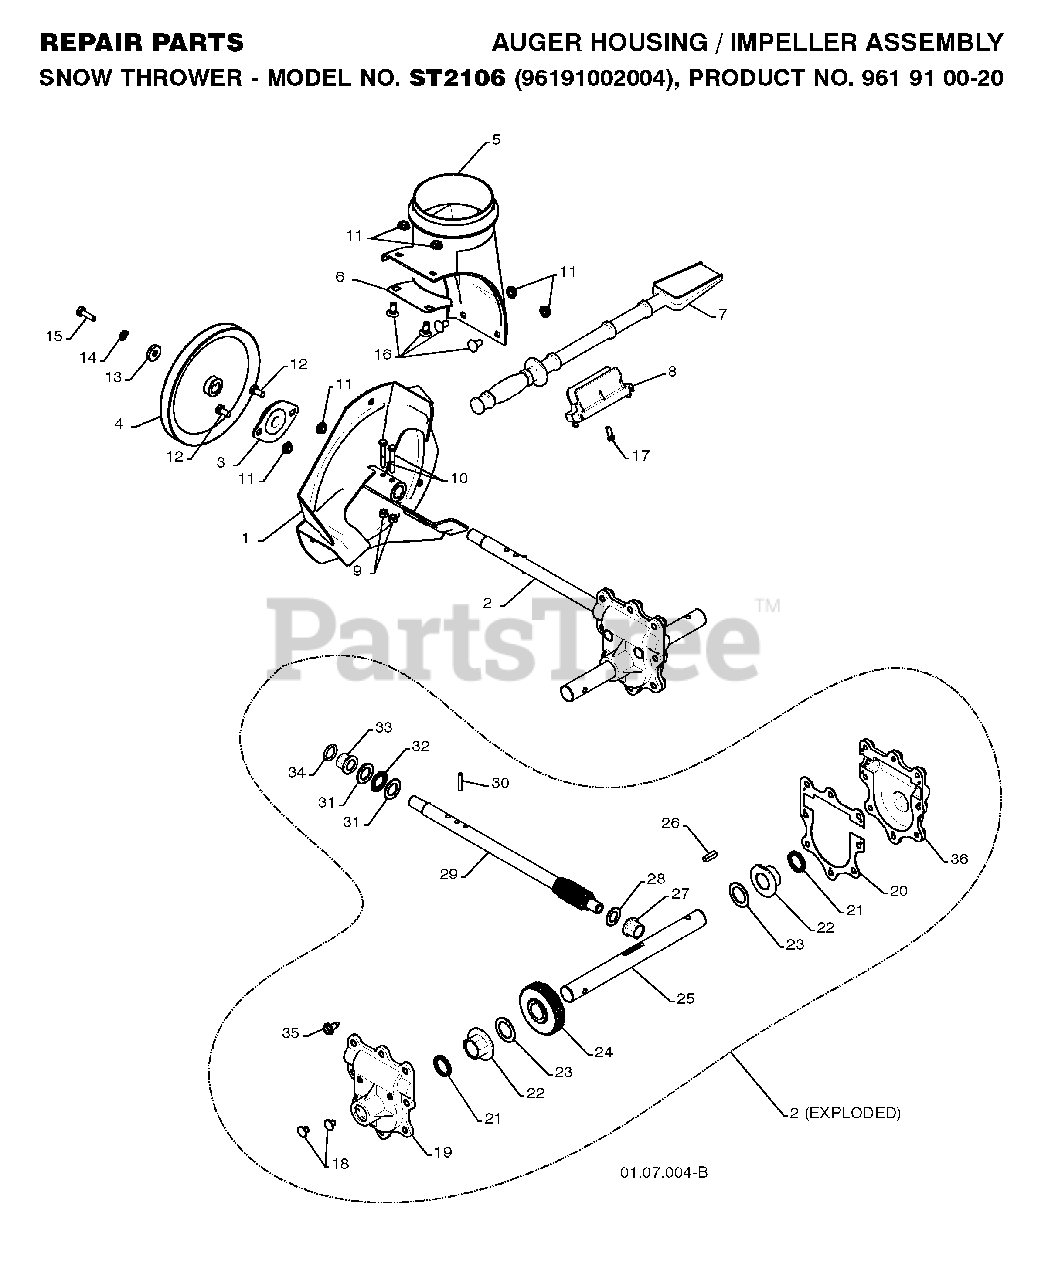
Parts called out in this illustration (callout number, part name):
1	IMPELLER ASSY
2	GEARBOX.ASSEMBLY.AUGER
3	BEARING FLANGE
4	PULLEY, IMPELLER
5	BASE DISCHARGE CHUTE
6	BRACKET, CORNER DISCHARGE
7	CLEAN OUT TOOL
8	CLIP.CLEANOUT.TOOL
9	LOCKNUT
10	SCREW.HEX.HD1/4-20X
11	NUT.FLANGE.5/16
12	BOLT, HEX HEAD 5/16-18
13	WASHER, FLAT
14	LOCKWASHER
15	CAPSCREW.HX.HD.5/16-18X1.00.NY
16	BOLT.CARRIAGE.5/16-18X
17	SCREW.HWH.13-16-5.8.BZP
18	CASE PLUG
19	GEARBOX HOUSING-RH
20	GEARBOX GASKET
21	OIL SEAL
22	FLANGE BUSHING-1"
23	WASHER TRUST 1"
24	WORM GEAR
25	AUGER SHAFT
26	KEY, SQUARE 1/4 X .875
27	FLANGE BUSHING-5/8
28	WASHER, THRUST 5/8
29	SHAFT, IMPELLER
30	PIN, ROLL 3/16 X 1-1/8
31	WASHER, THRUST 3/4
32	BEARING TRUST 3/4
33	BUSHING, FLANGE 3/4
35	HEX SCREW-5/16 X 3/4
36	GEARBOX HOUSING - LH
